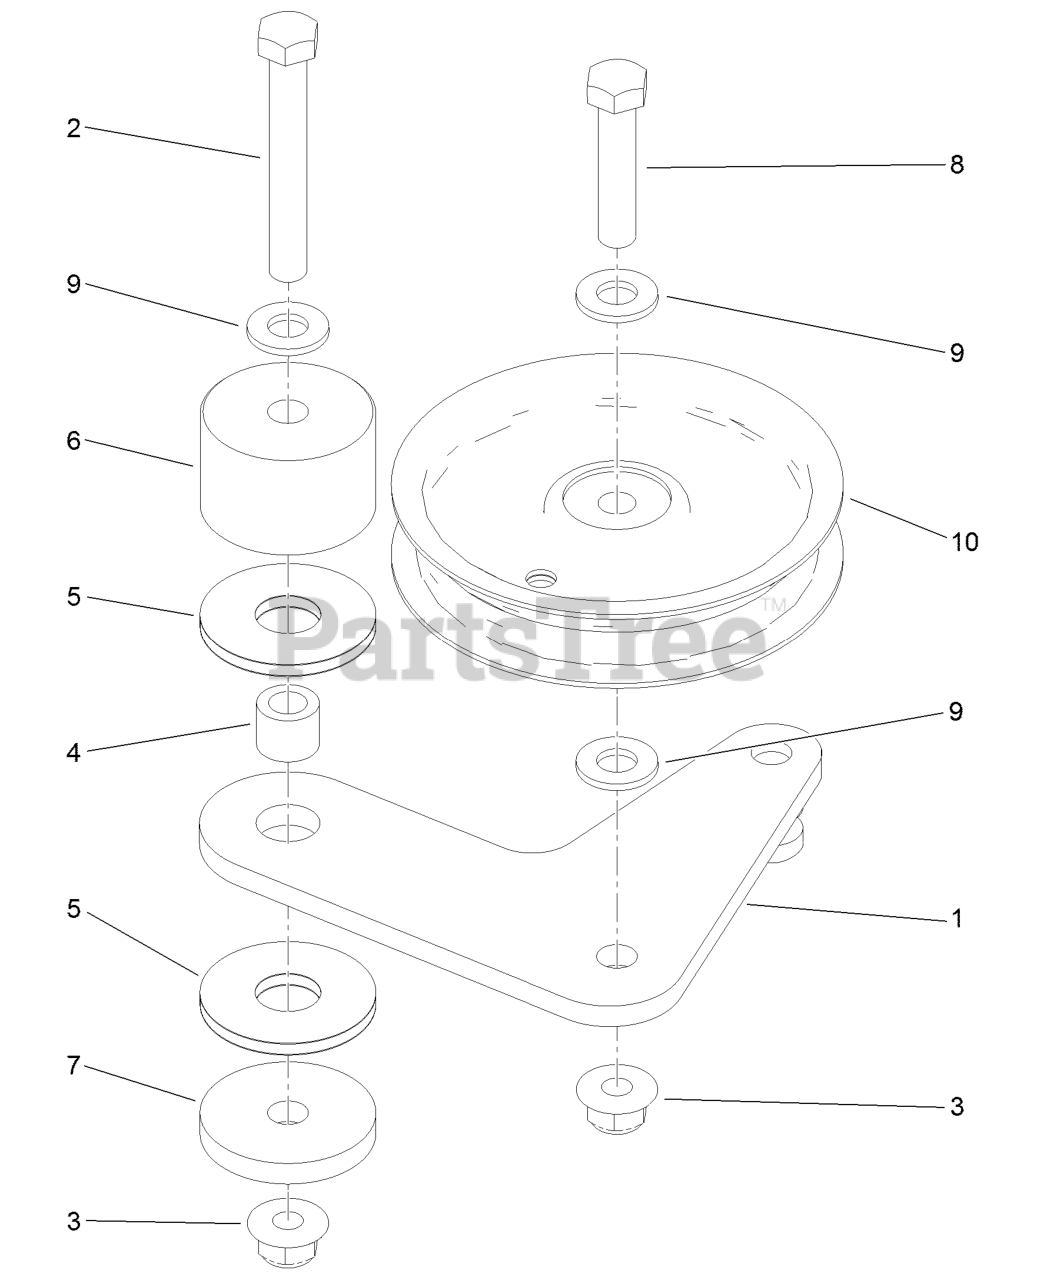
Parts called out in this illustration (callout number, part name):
1	PLATE-IDLER
2	SCREW-HH
3	NUT-HF, NI
4	BUSHING-LEVER, LIFT
5	WASHER-FRICTION, COMPOSIT
6	HUB-IDLER
7	WASHER-PLAIN
8	SCREW-HH
9	WASHER-FLAT
10	PULLEY-IDLER
